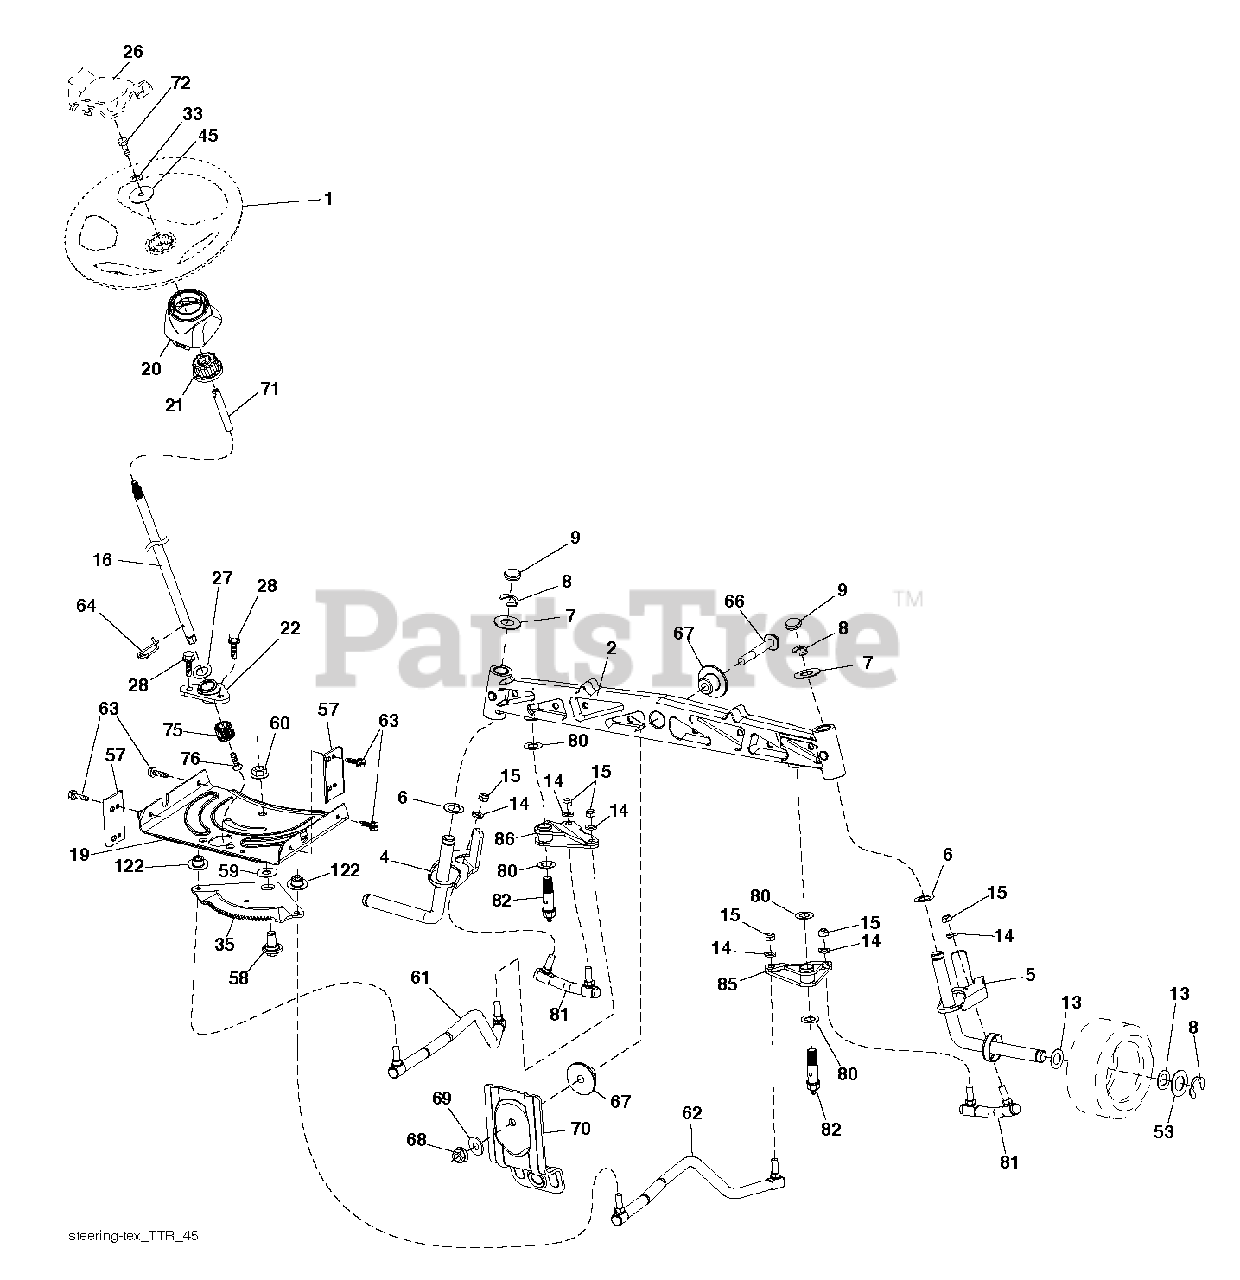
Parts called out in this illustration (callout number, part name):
1	WHEEL.STEERING.HARD.RIM.BLAC
2	RP SUBASM.AXLE.CAST.N
4	SPINDLE WELDMENT.SPIN
5	SPINDLE WELDMENT.SPIN
8	RING CLIP
9	CAP.SPINDLE.BLACK
14	WASHER, LOCK 3/8
15	NUT CROWNLOCK 3/8-24
19	PLATE.STEER.DDL.NLT/NG
20	BOOT.STEERING.PREDATOR.LT.BLAC
21	STEERING.WHEEL.ADAPTER
26	INSERT, WHEEL STEERING
27	WASHER LT
28	SCREW, 3/8-16X3/4
33	LOCKWASHER
35	GEAR GEAR.SECTOR.TEX.
45	WASHER.11/32
53	WASHER.HARDENED
57	BRACKET.UPSTOP.TEX
58	BOLT.SHOULDER.SECTOR.P
59	WASHER.THURST.SECTOR.S
60	NUT FLANGE LOCK 5/8-11
61	LINK SUBASM.LINK.DRAG
62	TUBE TUBE
63	SCREW
64	RETAINER.CLIP.SPRING.S
66	BOLT HEX FGHD 7/16-14 X 3 SERR
67	BUSHING.PM.FRONT AXLE
68	NUT.LOCK.FLANGE.7/16
69	WASHER.1.5X.505X.118
70	Deck Suspension Bracket, Front RR
71	SHAFT.EXTEN.STRG.SPLINE
72	BOLT 5/16-18 X 4 W/PATCH
76	Screw Head Socket Lrvb
80	THRUST WASHER
81	LINK SUBASM.LINK.CROS
82	SUBASM;PIVOT;BOLT;NZTR
85	PIVOT SUBASM.PIVOT.RH
86	PIVOT SUBASM.PIVOT.LH
122	CAP.GEAR.SECTOR.TEX
